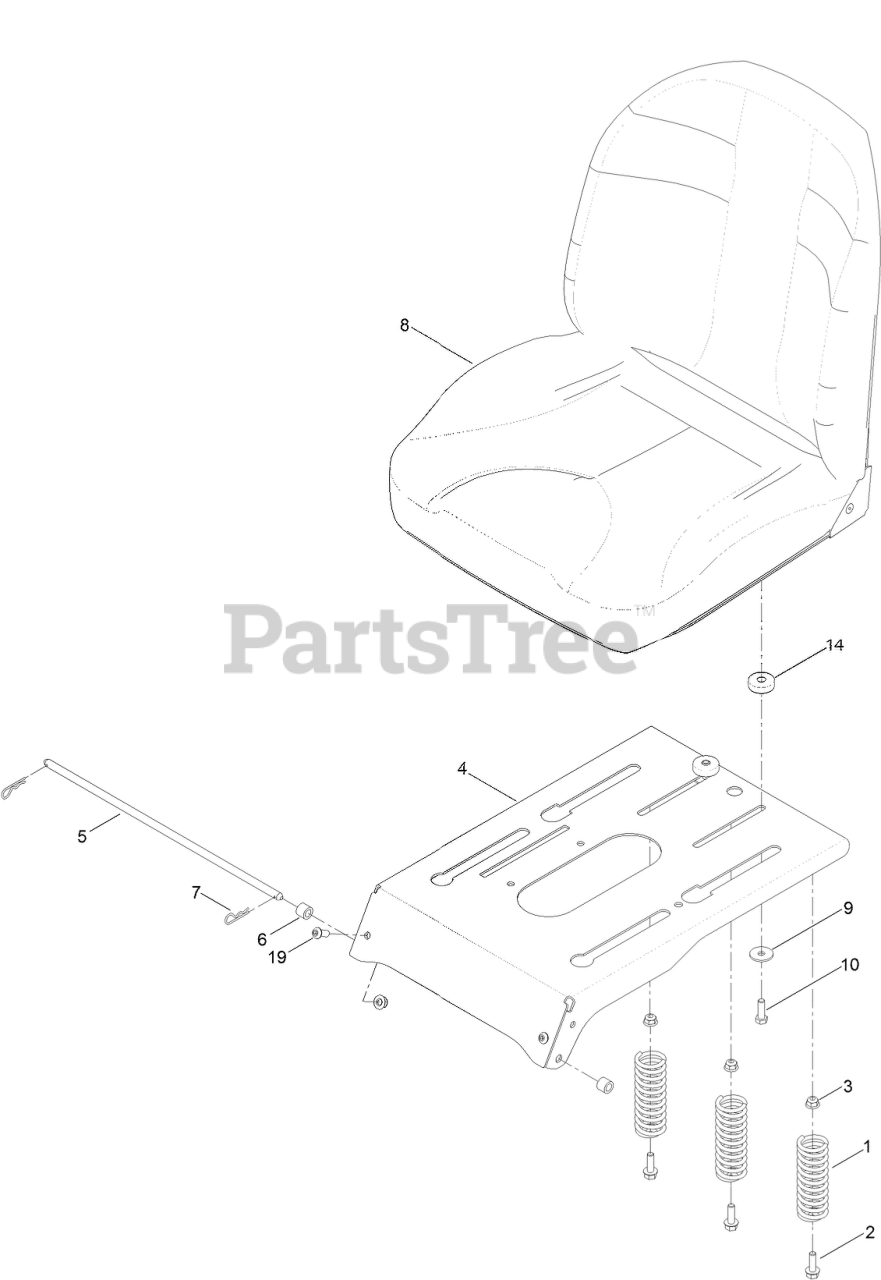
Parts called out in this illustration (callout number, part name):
1	SPRING-COMPRESSION
2	SCREW-HHF
3	NUT-HF, NI
4	PAN-SEAT, DELUXE
5	ROD-STOP
6	BUSHING-LEVER, LIFT
7	PIN-COTTER
9	WASHER-PIVOT
10	SCREW-HH
14	BUSHING-SLIDE, SEAT
19	SCREW-HSBH
